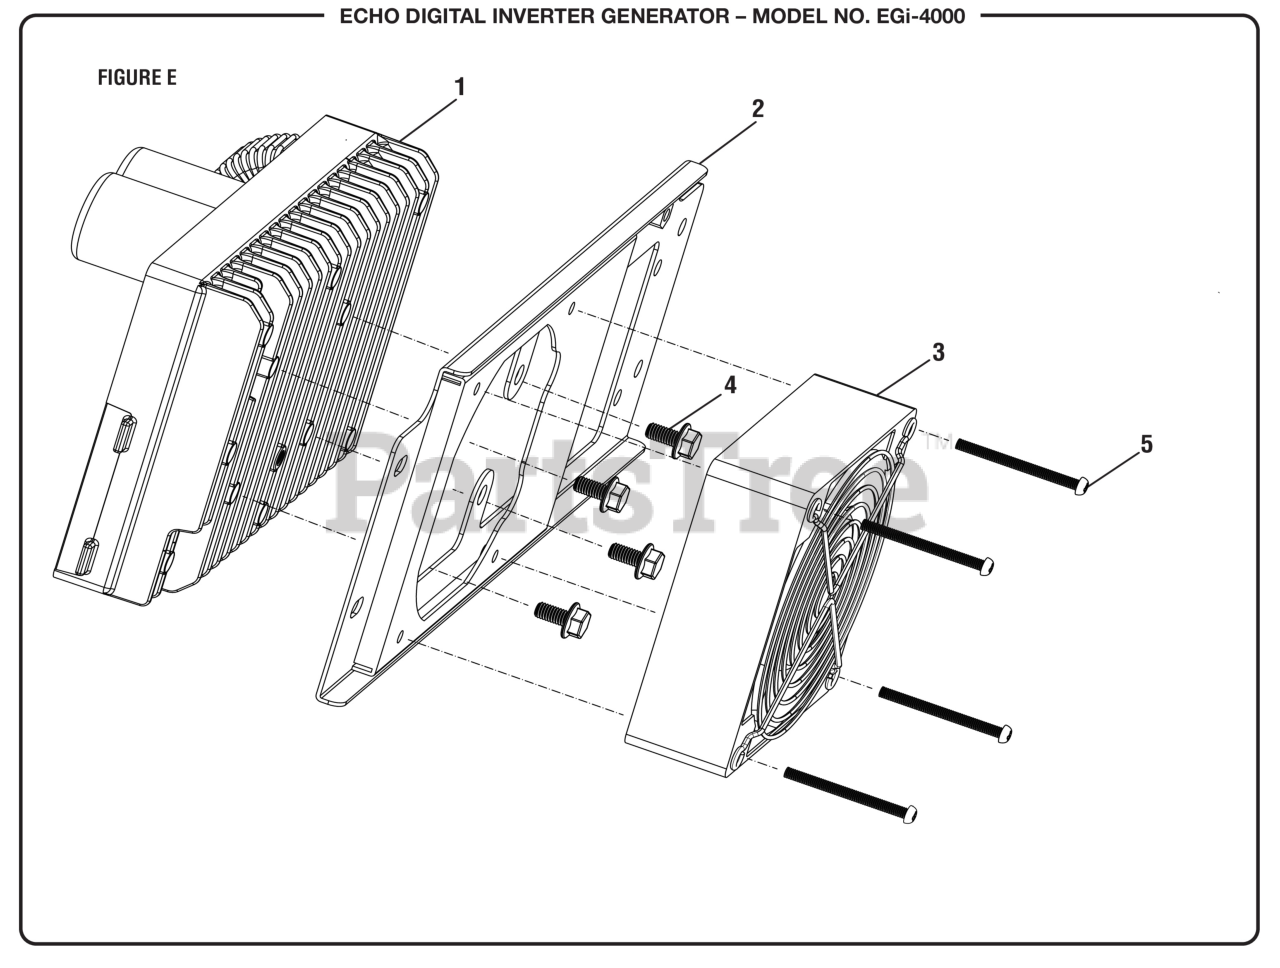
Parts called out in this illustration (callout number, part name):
1	Inverter Module
2	ASSY., INVERTER BRACKET
3	FAN, AC COOLING
4	BOLT, FLANGE HEX
5	SCREW, PHILIPS
